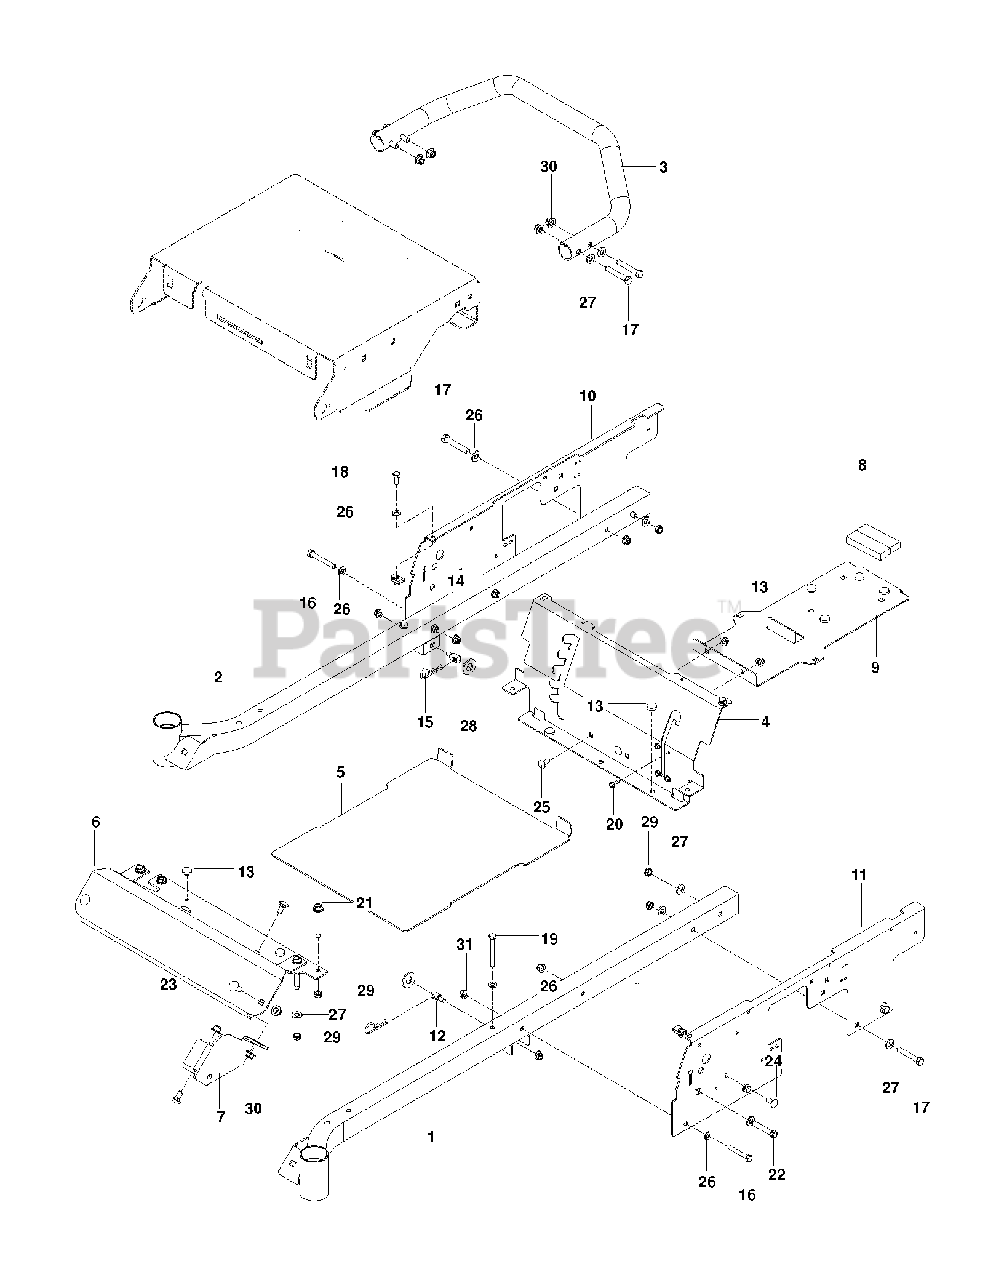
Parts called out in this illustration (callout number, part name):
1	FRAME, TUBE, LH, BLUE
2	FRAME TUBE, RH, BLUE
3	IMPACT BAR, BLUE
5	PAN, FLOOR W/DECALS, DIX
6	FOOT REST, BLUE
7	BRACKET, FRONT DECK, BLK
8	FOAM STRIP, FUEL TANK
9	SUPPORT, TANK/BATT, BLK
10	PLATE, RH SIDE, BLUE
11	PLATE, LH SIDE, BLUE
12	STUD.FASTNER.W/ANTI-ROTATE
13	GROMMET, BUMPER
14	U-CLIP 5/16-18 NUT RETAINER
15	HAIRPIN #4
16	CAPSCREW
17	HCS 3/8C X 2 1/4
18	HCS 5/16C X 3/4
19	HCS 5/16C X 2-3/4
20	SCREW 1/4 X 5/8
21	ENGINE BOLT, SPECIAL
22	HCS 1/2C X 2 3/4
23	RHSNB 3/8C X 1
24	RHSNB 3/8-16 X 3/4 GR5 ZD
25	BOLT 5/16C X 3/4" CARRIAGE
26	FLAT WASHER 5/16 SAE
27	WASHER 3/8 SAE FLAT
28	WASHER 5/8 FLAT
29	NUT HEX 3/8-16 NYLON, THIN
30	NUT 3/8-16 HEX FLG NYLOC ZD
31	5/16-18 NYLOC FLANGE NUT
